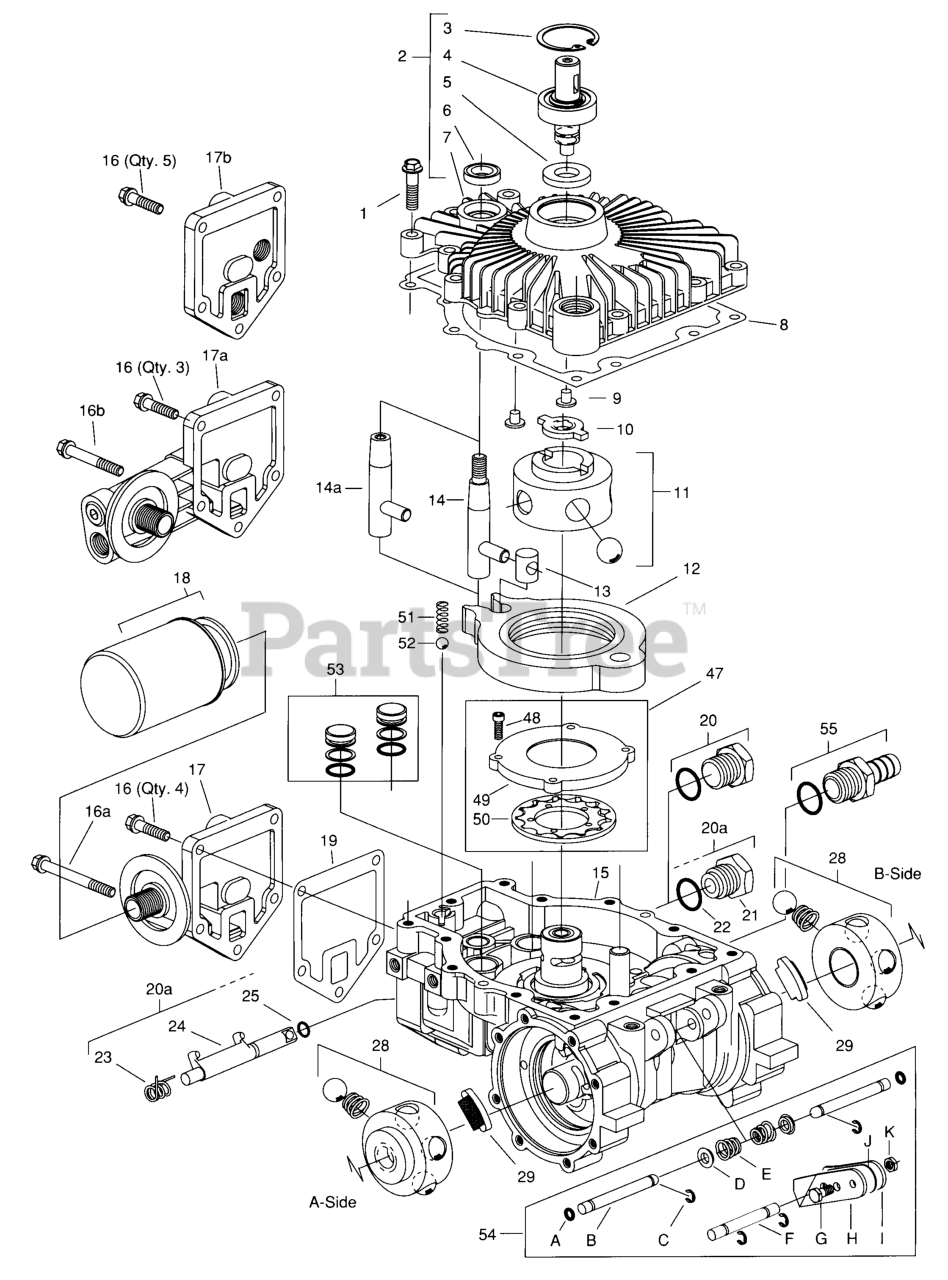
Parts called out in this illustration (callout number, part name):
1	Screw, 1/4-20 Self Tap
3	Internal Retaining Ring
5	SEAL,INPUT SHAFT
6	SEAL,CONTROL SHAFT
8	COVER GASKET
14	Control Shaft, S/A
16	Screw, 1/4-20 Hex Flange
16B	Screw, 1/4-20 Hex Flange
17A	FILTER BASE S/A
18	Filter, (W/Seal)
22	Dump Valve Nut, O-Ring
23	DUMP VALVE SPRING
28	MOTOR ROTOR BALL
31	BACKUP PLATE
33	RING GEAR 57T
35	PRIMARY CARRIER 15T
38	SECONDARY CARRIER SA
39	Tapered Axle Kit, LH B
39A	Tapered Axle Kit, LH B
41	External Retaining Ring
42	THRUST WASHER
43	Internal Retaining Ring
49	PLATE,PUMP CLASSII (EATON
50	GEROTOR S/A CHRG PMP
54	Brake Lever Parts
A	QUAD SEAL
